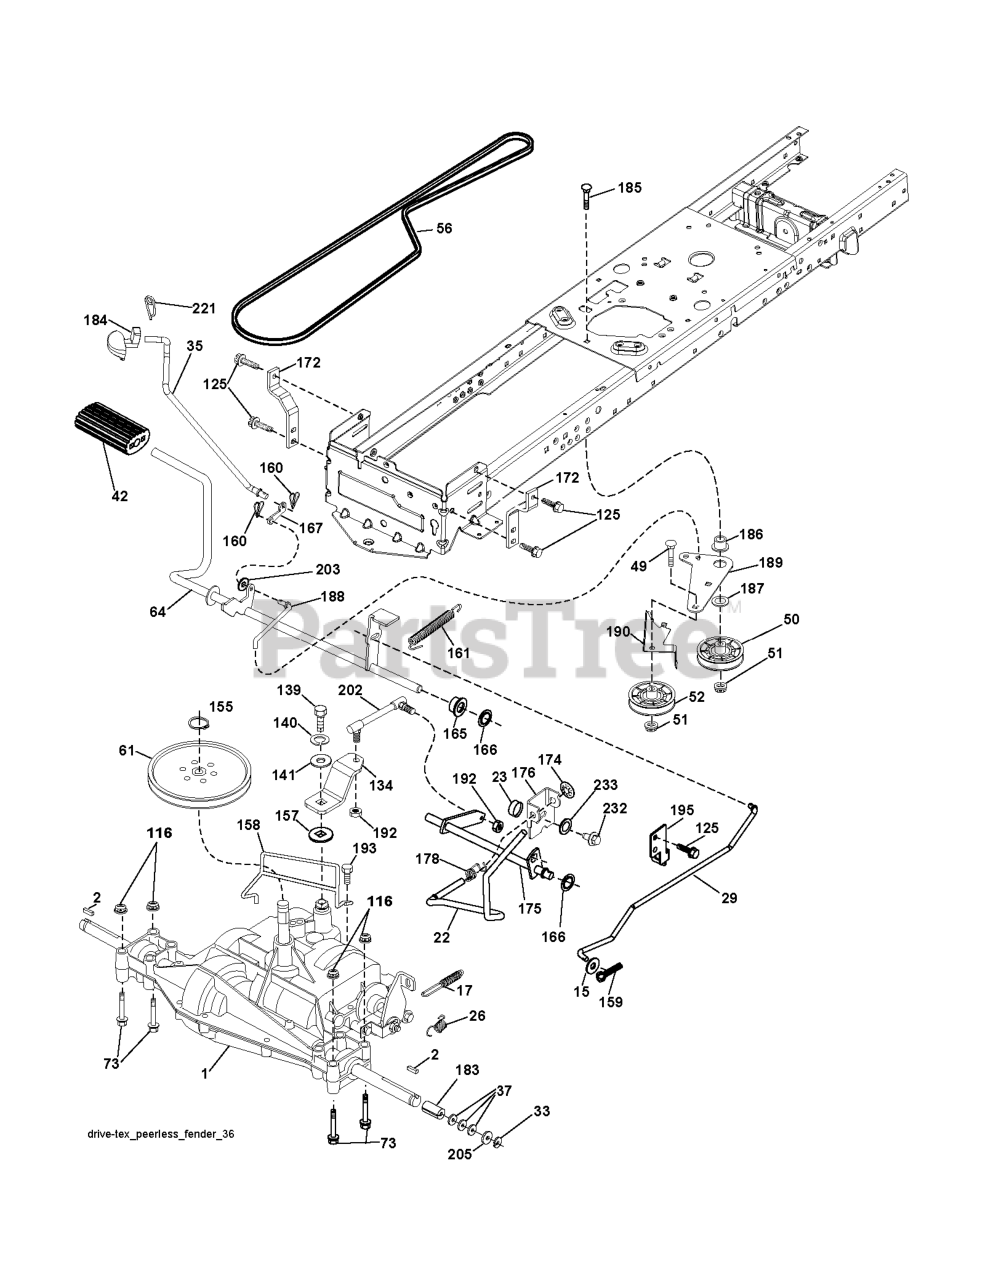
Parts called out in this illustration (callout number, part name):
2	SQUARE KEY
15	WASHER
17	SPRING.BRAKE.PEERLESS.TEX
22	ROD.SHIFT.FENDER.TLT.2006
23	KNOB.DUCKHEAD.1/2
26	SPRING.BRAKE.RTN.GR.DR
29	ROD.BRAKE.PEERLESS
35	ROD.CNTRL.PARK.PREDATOR.LT.TEX
42	PEDAL COVER T
50	IDLER.FLAT.910.OFFSET
51	NUT LOCK FLG 3/8-16 UNC
52	IDLER.V-GROOVE.910.OFFSET
56	V-BELT.TRACTOR.DRIVE.P
61	PULLEY TRANS
64	SHAFT.ASM.PEDAL.BRAKE.
73	BOLT HEX 5/16-18 GR 5
116	NUT LOCK HEX FLANGE 5/16-18
125	SCREW
139	BOLT 1/4-28X3/4
140	LOCKWASHER
155	RETAINING RING LT
157	WASH-SHFT PLT LT
158	KEEPER.PMS.18/20.D4365
159	COTTER PIN
160	RETAINER CLIP
161	SPRING, RETURN LT
165	BUSHING.SHAFT.BRAKE.HAND
166	NUT.PUSH.625
167	LATCH.BRAKE.SPRING
172	STRAP.TRQ.LH.GEAR.DRIV
174	NUT.PUSH.500.2006
175	SHAFT ASM SHIFT
176	ARM.CLEVIS.ROD.SHIFT
178	SPRING.SHIFT.GT2006
183	SPACER AXLE
184	HANDLE PARKING BRAKE
186	SPACER.RETAINER
187	WASHER 12/32X2X10GA
188	RP.LINK.CLUTCH.GROUND.DRIVE
189	BELLCRANK.GROUND.DRIVE.TEX.
190	KEEPER.BELLCRANK.DRIVE
192	NUT LOCK CENTER 1/4 -28 FNTHD
193	SCREW 5/16"
195	BRKT.ROD.BRAKE.PEERLES
202	LINK.SHIFT.PMST.18" (SPG1286)
203	WASHER
221	RETAINER.SPRING.CLIP.H
232	BOLT FIN HEX 7/16-14 X 1
233	WASHER SERRATED
